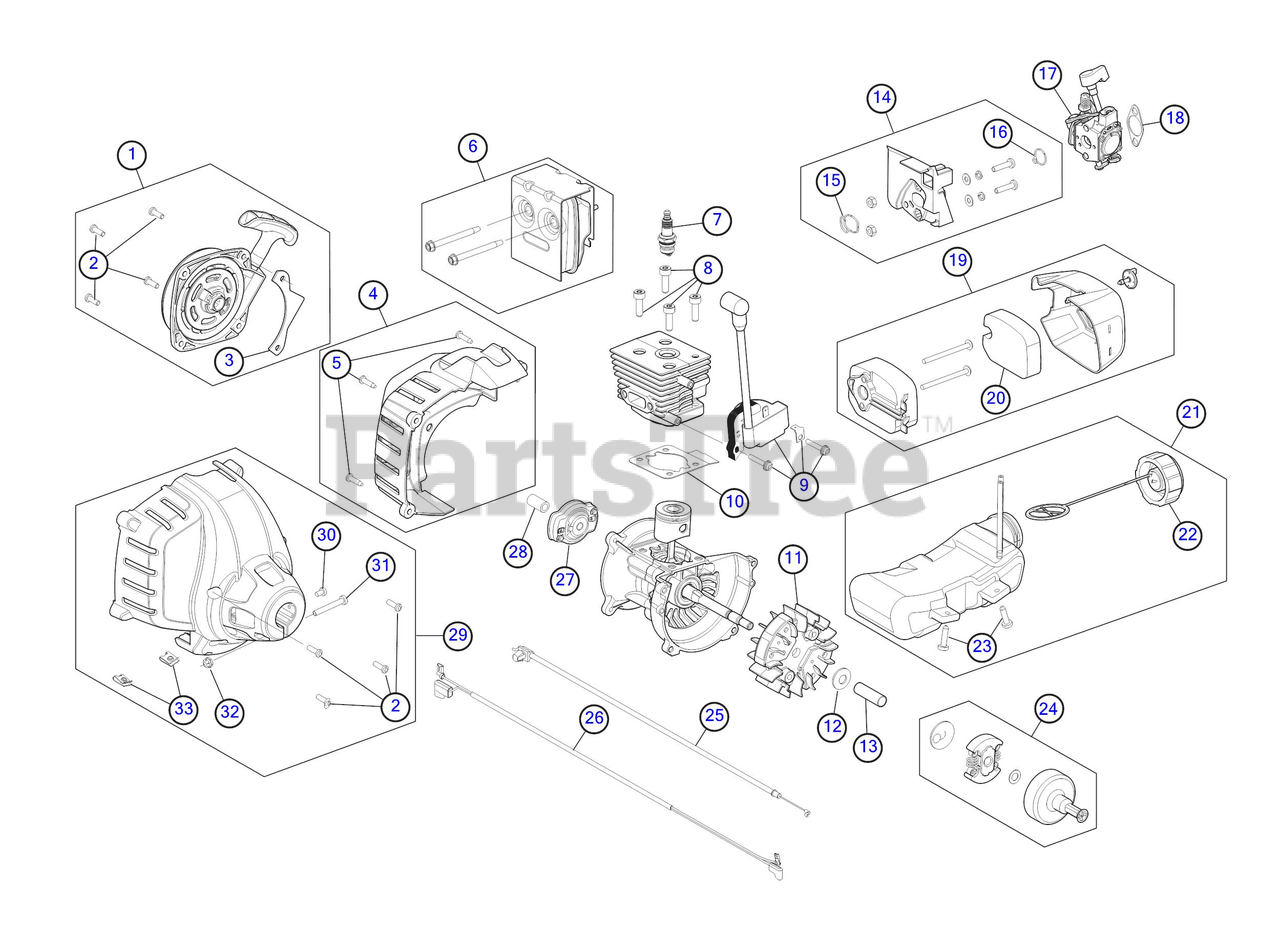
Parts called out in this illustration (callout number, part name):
1	Starter Assembly
2	Starter Screw
3	Starter Assembly Guard
4	Rear Engine Cover
5	Cover Screw
6	Muffler Assembly
7	Spark Plug
8	Cylinder Bolt
9	Module Assembly
10	Cylinder Gasket
11	Flywheel Assembly
14	Insulator Assembly
15	Insulator O-Ring
16	Carburetor O-Ring
17	Carburetor
18	Carburetor Gasket
19	Air Cleaner Assembly
20	Air Cleaner Filter
21	Fuel Tank Assembly
22	Fuel Tank Cap
23	Fuel Tank Screw
24	Clutch Assembly
25	Throttle Cable
26	Lead Wires
27	Pawl Assembly
29	Clutch Cover Assembly
30	Anti-rotation Screw
31	Clamp Screw
32	Clamp Nut
33	U-shaped Nut
